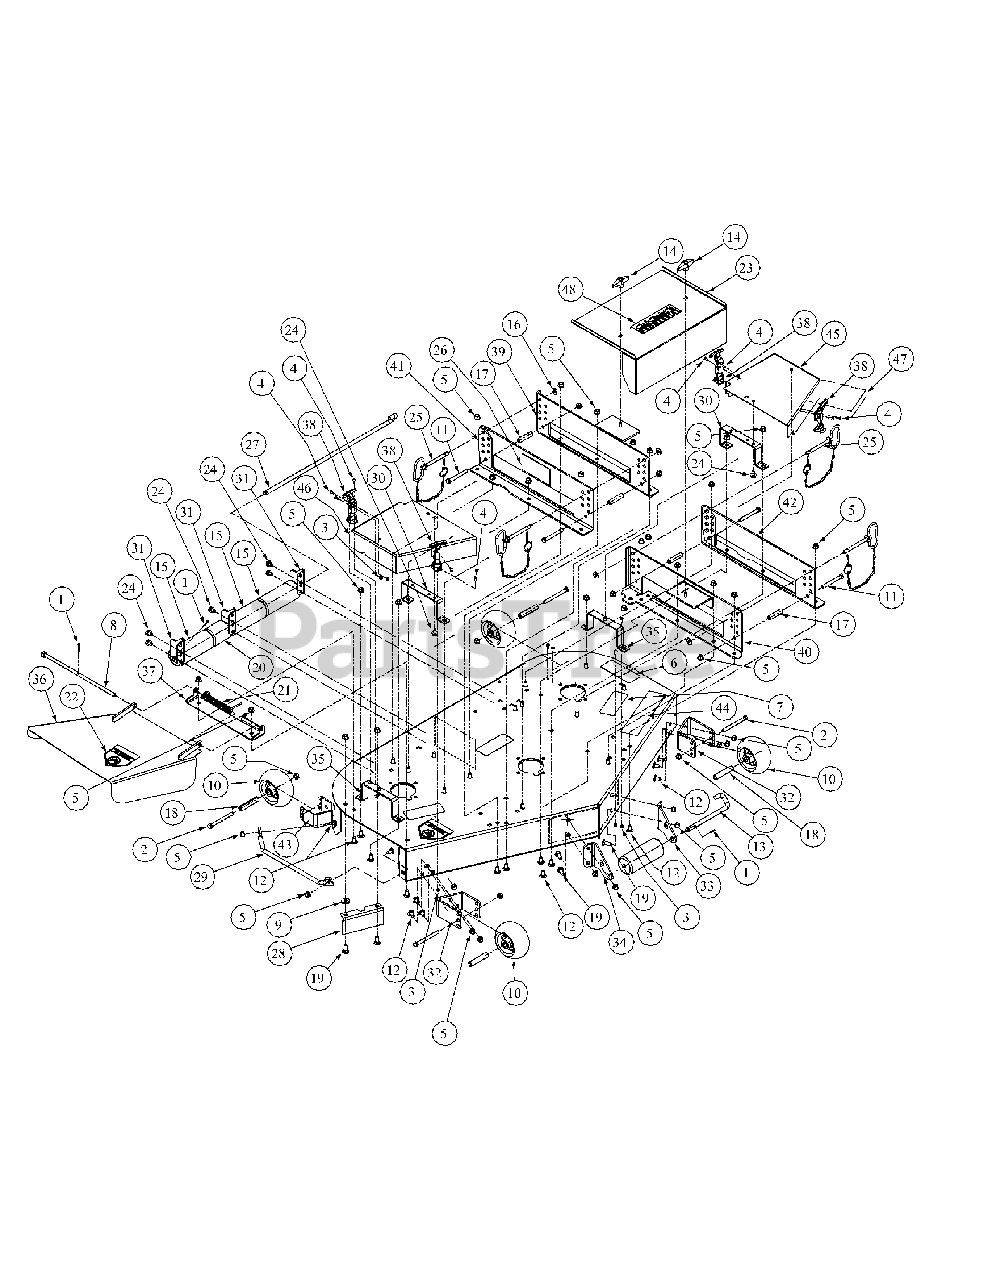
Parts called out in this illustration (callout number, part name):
1	Cotter Pin, .125 Dia. x 1.0
2	Hex Cap Screw, 3/8-16 x 3.75
3	Lock Nut, Nylon Insert, #10-32
4	Phillips Head Screw, #10-32 x 1/2
5	Flange Lock Hex Nut, 3/8-16
6	Decal Rotating Blade
7	Decal Warning Shield Missing
8	Deflector Pin Pivot Assembly
9	Idler Washer
10	Wheel, 5.00 Dia.
11	Hex Cap Screw, 3/8-16 x 3.25 Lg.
12	Carriage Bolt, 3/8-16 x .75 Lg.
13	Roller Pin, 1/2 Dia. x 7.31 Lg.
14	Knob Assembly Wingnut, 5/16-18
15	Front Roller
16	Flat Washer, .385 ID x .870 OD x .092
17	Spacer Stop Deck
18	Wheel Spacer
19	Carriage Bolt, 3/8-16 x 1
20	Grass Catcher Frame Roller
21	Torsion Spring
22	Decal, Danger Hands and Feet
23	Center Belt Cover
24	Hex Index Washer Screw, 3/8-16 x .5
25	Deck Pin 3/8 Dia.
26	Label, Cut Height
27	Roller Pin
28	Chute Bracket
29	Finger Guard
30	Belt Cover Support
31	Roller Mount Bracket
32	Anti-Scalp Wheel Front Mount Bracket
35	Outer Belt Support Cover Assembly
36	Chute Assembly
37	Chute Bracket Weldment
38	T-Handle Latch Draw
39	Right Hand Inner Hanger Assembly
40	Left Hand Inner Hanger Assembly
41	Right Hand Outer Hanger Assembly
42	Left Hand Outer Hanger Assembly
43	48" Deck Weldment
44	Label Commercial Mower
45	Left Hand Belt Cover Weldment
46	Right Hand Belt Cover Weldment
47	Label Mower Deck
48	Label Commercial Mower Deck
